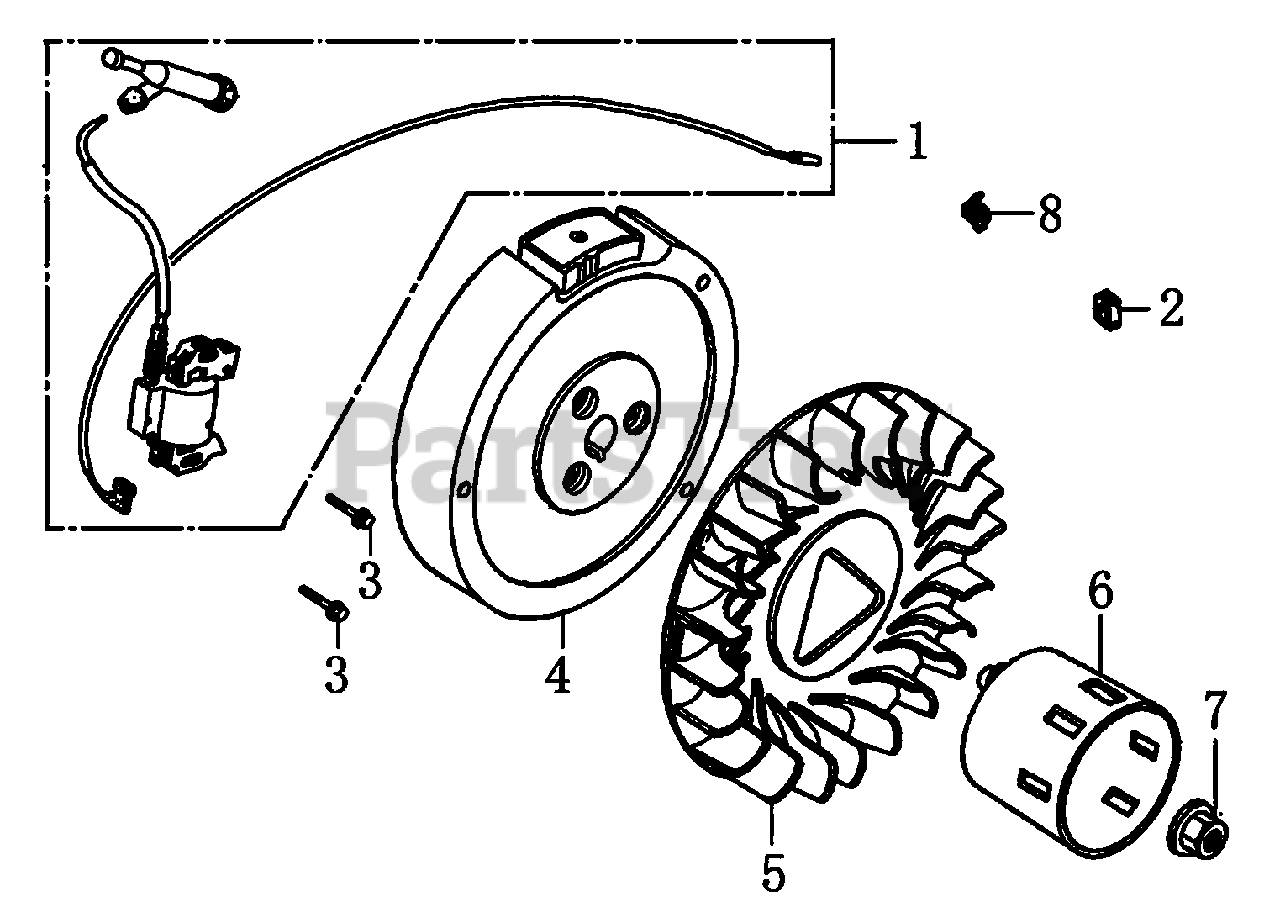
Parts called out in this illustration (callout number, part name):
1	COIL ASSY., IGNITION
2	GROMMET, CORD
3	BOLT, FLANGE, M6X25
5	FAN, COOLING
6	PULLEY, STARTER
7	NUT, SPECIAL, 16MM
8	HOLDER, STOP SWITCH
